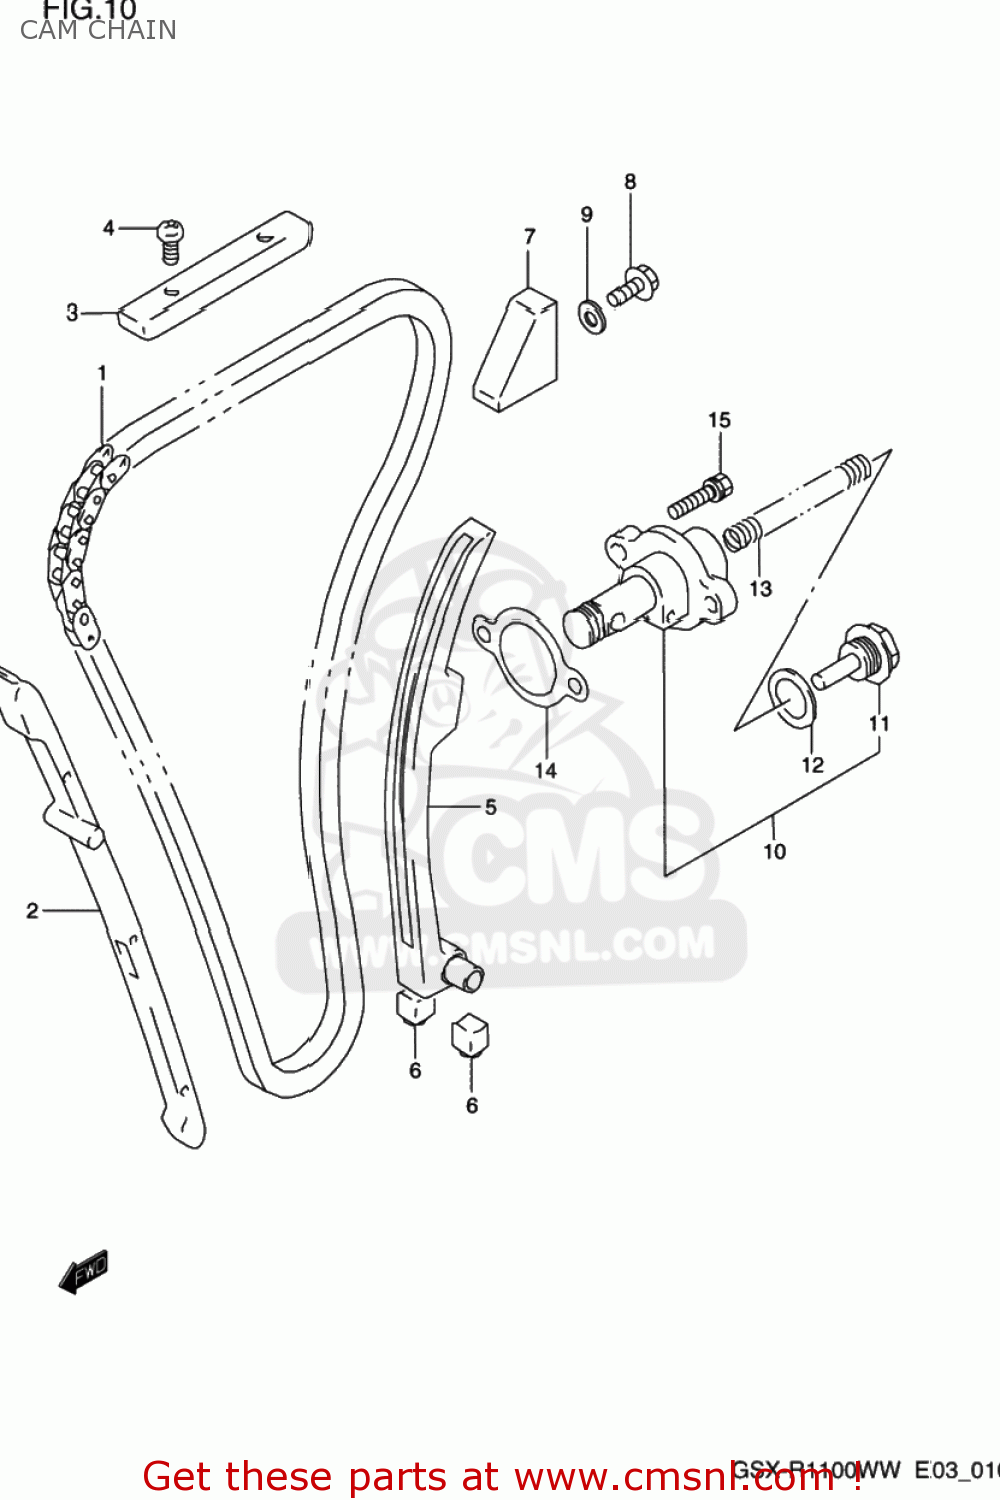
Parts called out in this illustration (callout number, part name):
1	CHAIN,CAMSHAFT DRIVE
2	GUIDE,CAM CAHIN NO.1
3	GUIDE,CAM CHAIN NO.2
4	SCREW
5	TENSIONER,CAM CHAIN
6	CUSHION,CAM CHAIN TENSIONER
7	GUIDE,CAM CHAIN NO.3
8	BOLT
9	GASKET(5.8X13X1.2) (NAS)
10	ADJUSTER ASSY,TENSIONER
11	PLUG
12	GASKET (NAS)
13	SPRING
14	GASKET,TENSIONER ADJUSTER (NAS)
15	BOLT
